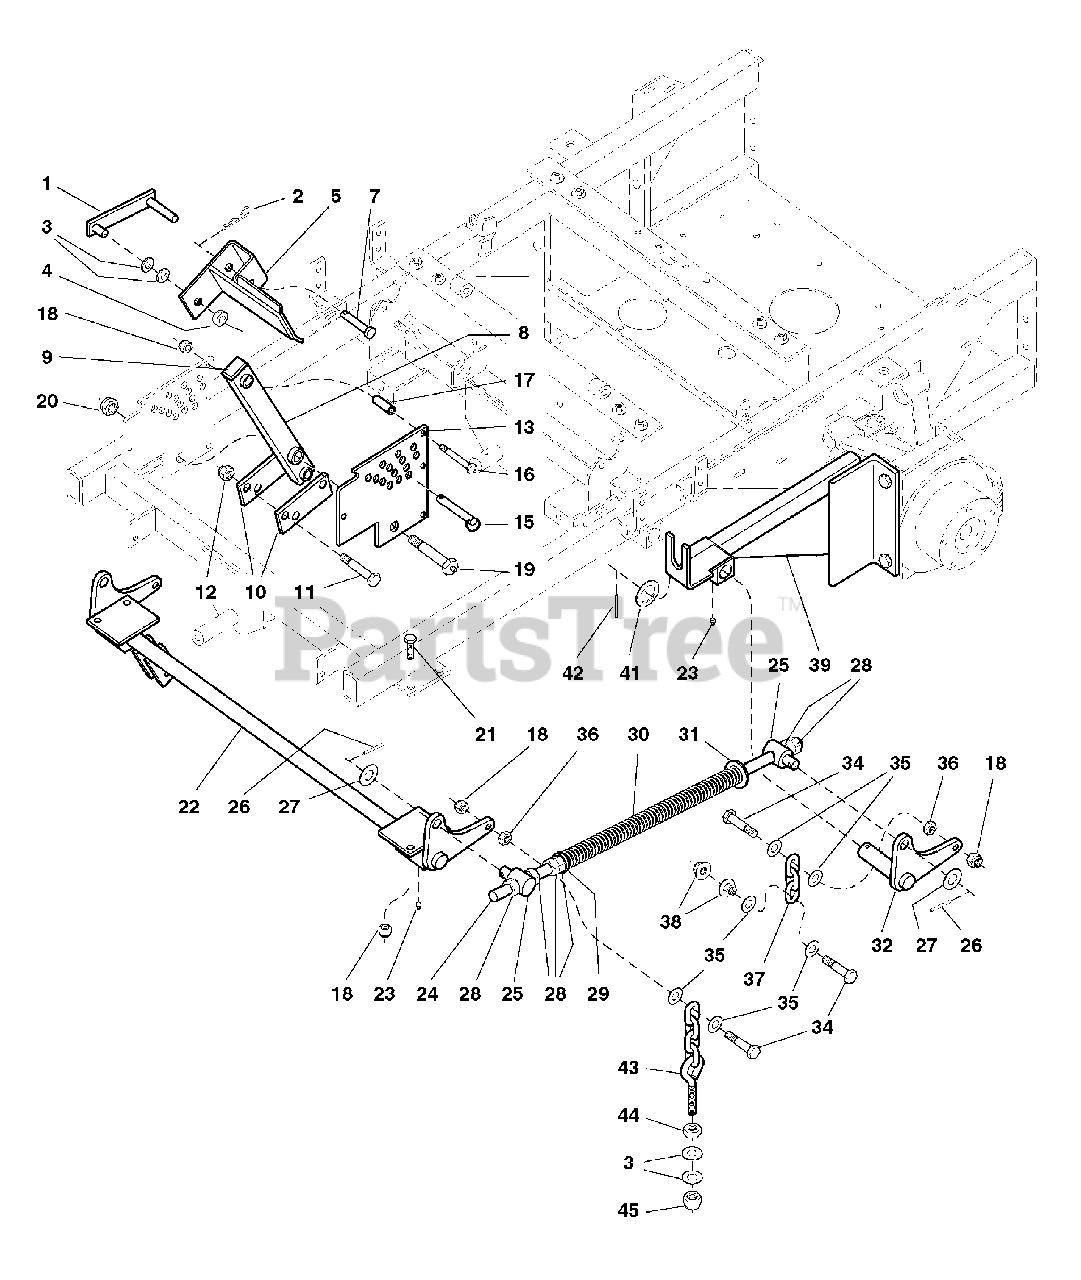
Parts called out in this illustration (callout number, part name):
1	DECK LIFT LOCK
2	HAIRPIN CLIP
3	WASHER, 1/2
4	COLLAR, 1/2 Set
5	DECK LIFT PEDAL
7	PIN, Clevis, 1/2 x 2-1/2
8	ARM, Deck Lift Pivot
10	LINK, Deck Lift
11	CAPSCREW, Hex Hd, 1/2-20 x 3
12	NUT, Hex, Nylon Lock, 1/2-20
13	DECK HEIGHT PLATE
15	PIN, 1/2 x 3
16	CAPSCREW, Hex Hd, 3/8-16 x 2-3/4
17	SPACER, Lift Plate
18	NUT, Hex, Nylon Lock, 3/8-16
19	LIFT PIVOT BOLT
20	NUT, Hex Jam, Nylon Lock, 5/8-11
21	CAPSCREW, Hex Hd, 3/8-16 x 1-1/4
22	DECK LIFT SHAFT & MOUNT ASSEMBLY
23	GREASE FITTING
25	SPRING ROD PIVOT
26	PIN, Spring, 3/16 x 1-1/4
27	WASHER, 5/8
28	NUT, Hex, 5/8-11
30	SPRING, Deck Lift
31	WASHER, USS, 5/8
32	DECK LIFT PIVOT-LH
34	CAPSCREW, Hex Hd, 3/8-16 x 1-3/4
35	WASHER, 3/8
36	NUT, Hex Jam, 3/8-16
37	CHAIN, 3 Links
38	NUT, Hex, Serrated Flange, 3/8-16
39	REAR DECK LIFT FRAME-LH
42	PIN, Roll, 3/16 x 1-1/2
43	HANGER, FRONT DECK - 4 LINK, 5.5" EB
44	NUT, Hex, 1/2-13
45	NUT, Hex, Nylon Lock, 1/2-13
